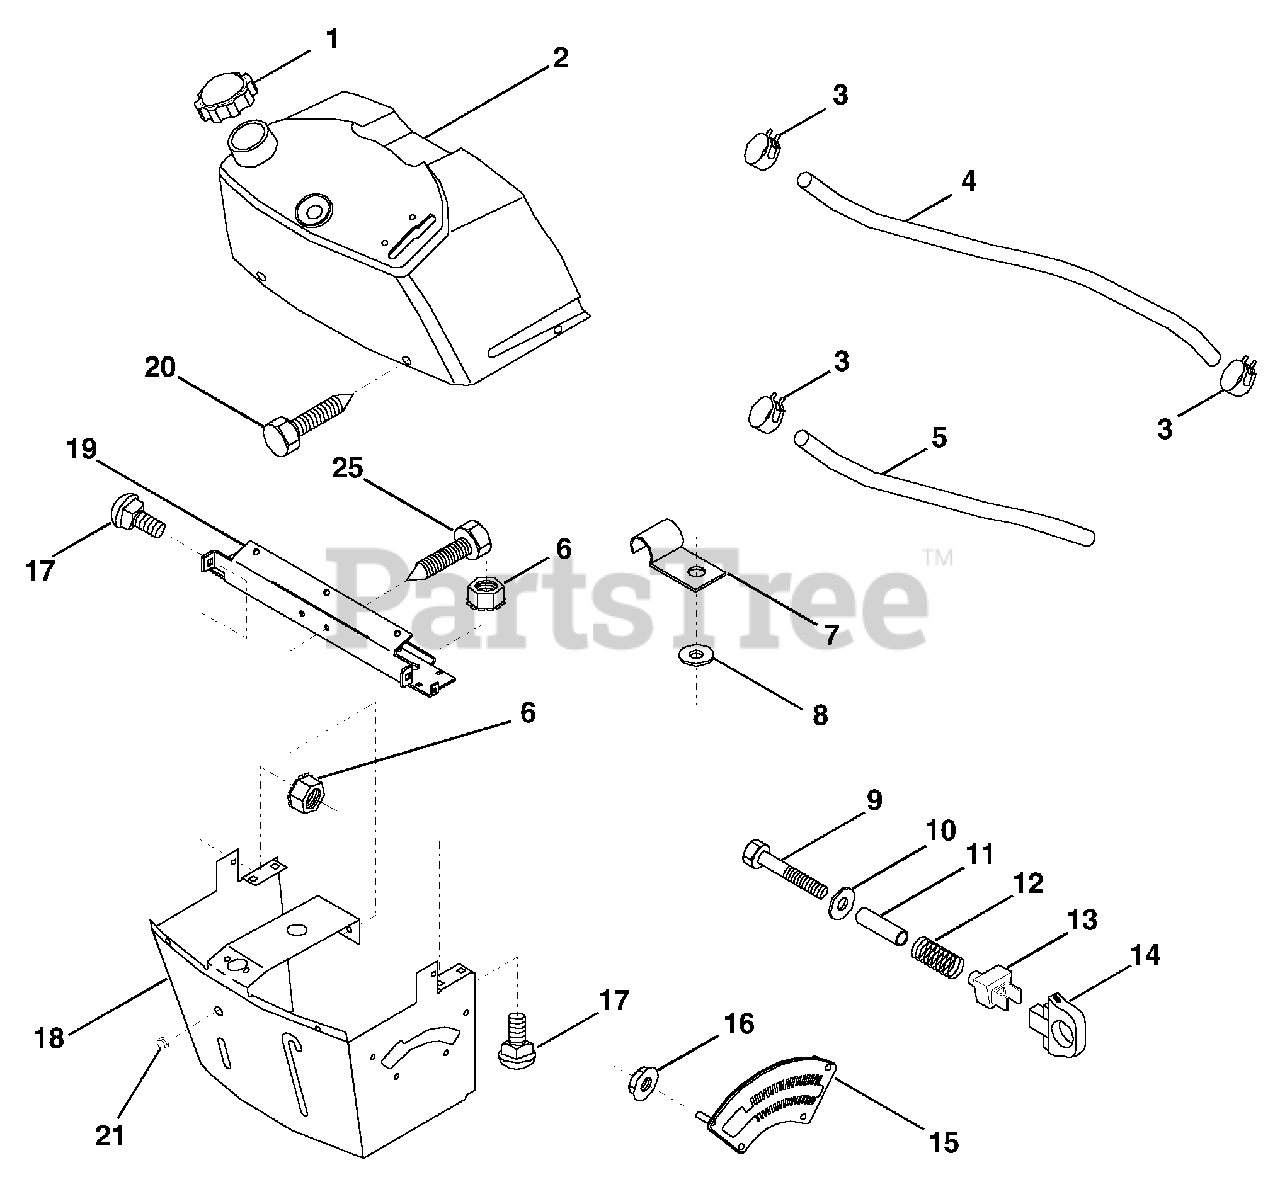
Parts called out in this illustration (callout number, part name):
2	Assembly, Dash & Fuel Tank
3	Clamp, Hose
4	Line, Fuel
5	Line, Fuel
6	Nut, Hex, Keps 1/4-20
7	Clip, Fuel Line
8	Washer 9/32 x 3/4 x 16 Ga.
9	Bolt, Hex, Fin 1/4-20 x 1-3/4
10	Washer 11/32 x 11/16 x 16 Ga.
11	Spacer, Split
13	Clip, Height Adjustment
14	Knob, Height Stop
15	Adjustment, Quadrant Height
16	Nut, Self-Threading 3/16-18
17	Bolt, Carriage 1/4-20 x 1/2 Gr. 5
18	Support Assembly, Dash
19	Brace, Cross
20	Screw, Self-Tapping 1/4-20 x 1/2
21	Plug Dome Black
25	Screw Hex Thd Cut 1/4-20 x 5/8
